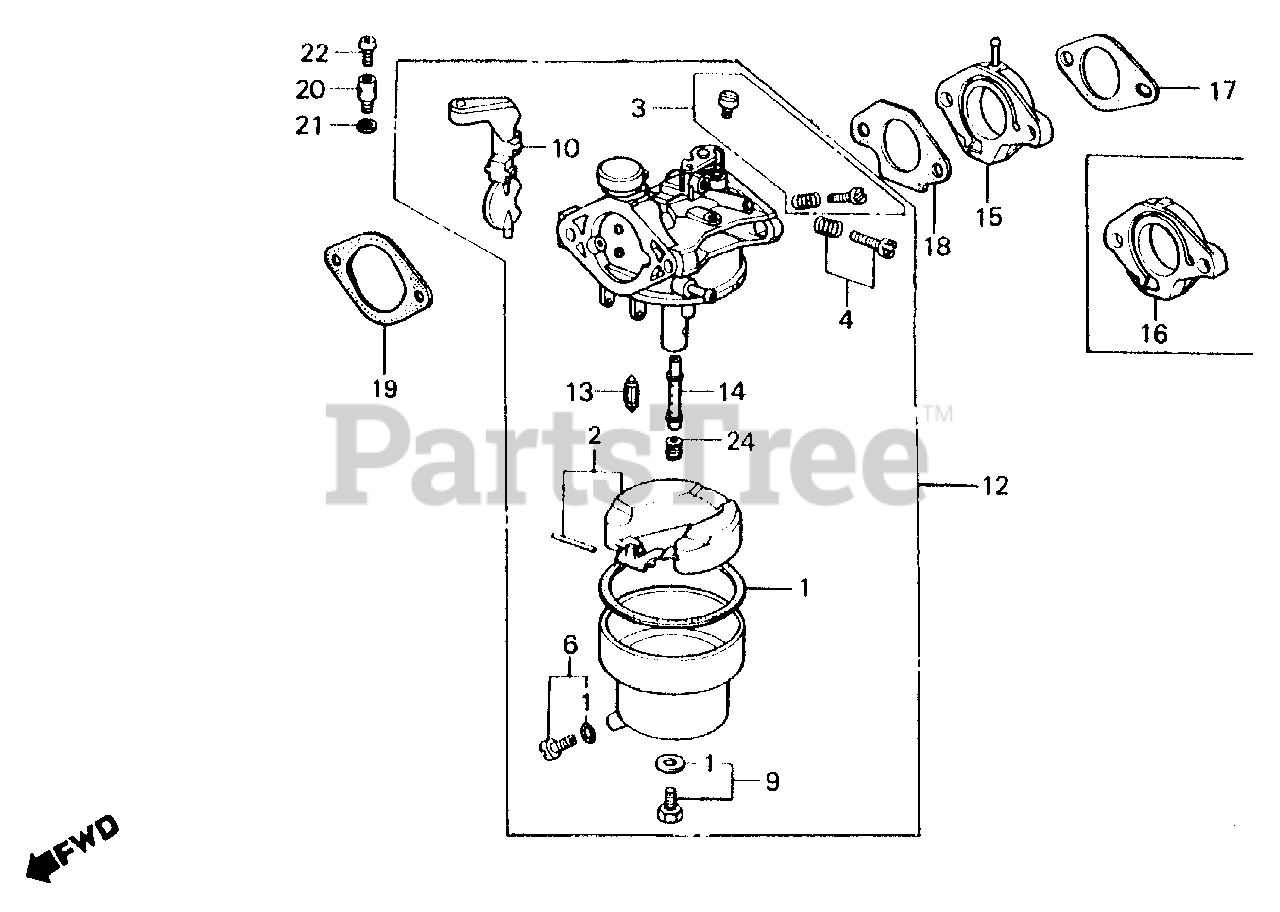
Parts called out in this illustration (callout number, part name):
1	GASKET SET
3	SCREW SET A
4	SCREW SET A
6	SCREW SET, DRAIN
9	SCREW SET B
12	CARBURETOR ASSY.
13	VALVE, FLOAT
14	NOZZLE, MAIN
15	INSULATOR, CARBURETOR (NOT AVAILABLE)
17	GASKET, INSULATOR
18	GASKET, CARBURETOR
19	GASKET, AIR CLEANER
20	HOLDER, CABLE
21	CIRCLIP (5MM)
22	SCREW, PAN (4X8)
24	JET, MAIN (#82)
24	JET, MAIN (#85)
24	JET, MAIN (#88)
24	JET, MAIN (#90)
NI	CHAMBER SET, FLOAT
